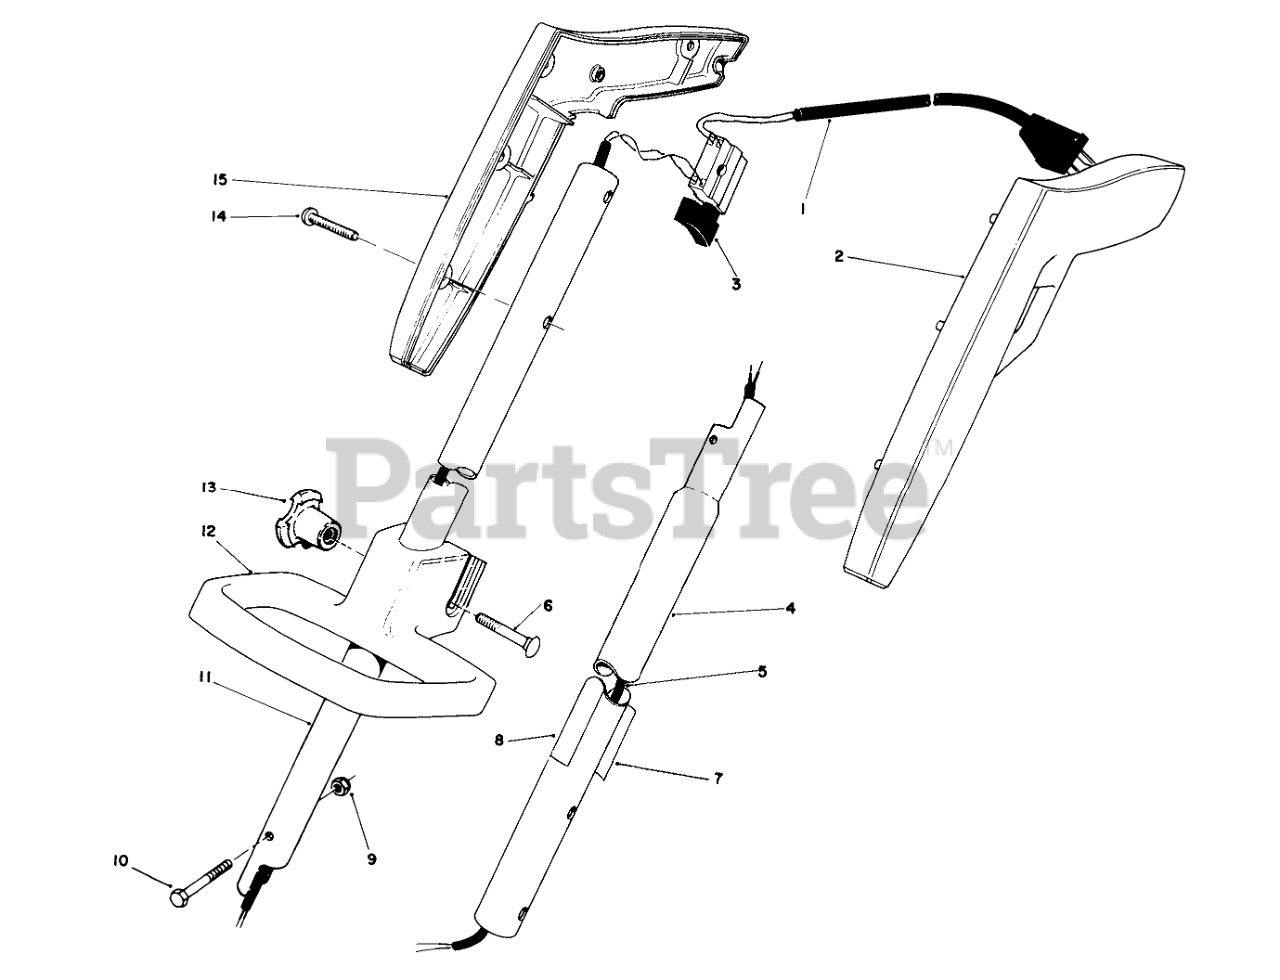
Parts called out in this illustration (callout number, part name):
1	Power Cord
2	Grip L.H.
3	SWITCH SINGLE SPEED
4	LOWER TUBING
5	1010 WIRE HARNESS
6	BOLT-CARR
7	Decal-Serial (Canada)
8	Decal
9	NUT-LOCK, NI
10	HEX HD MACHINE SCREW
11	UPPER EXT TUBING
12	Handle
13	Knob
14	Screw
15	R.H. GRIP
